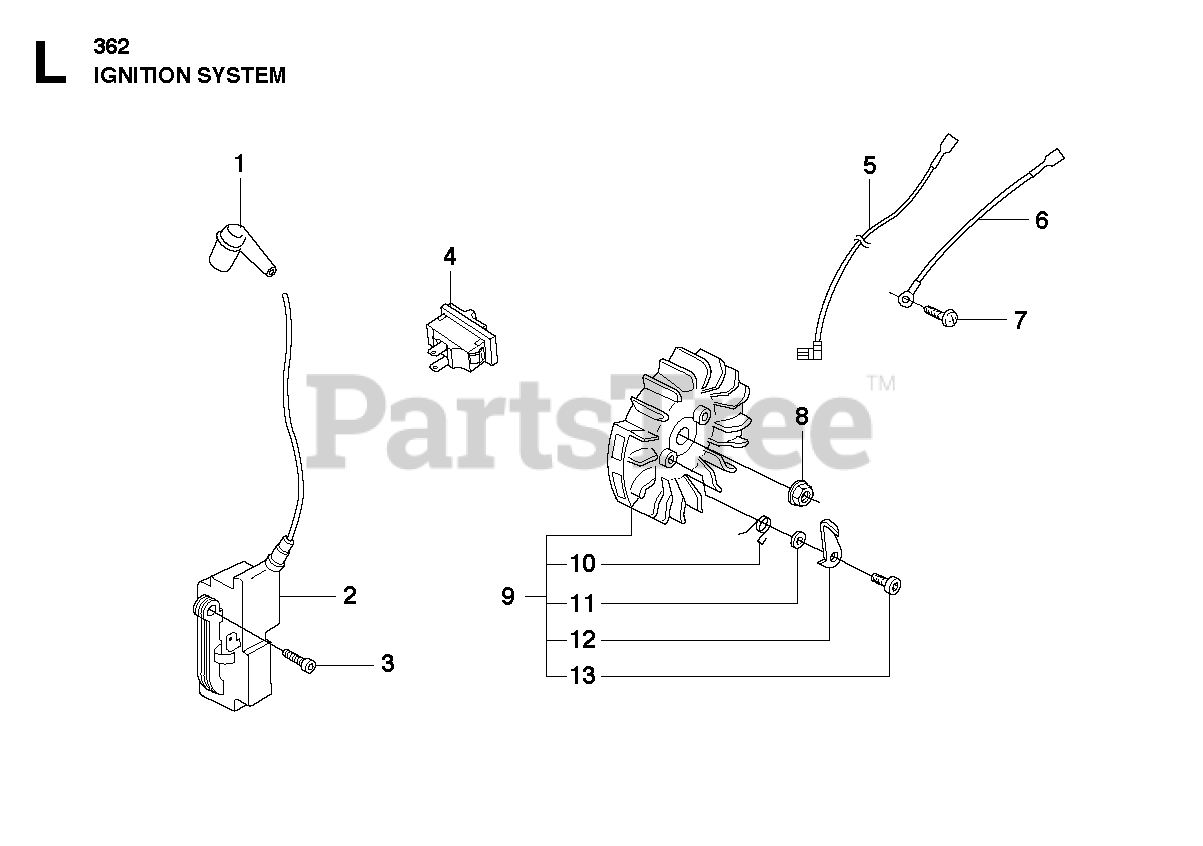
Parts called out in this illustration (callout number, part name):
1	SPARK PLUG CONN. KIT
2	IGNITION MODULE
4	START/STOP SWITCH
8	NUT W/ WASHER
10	SPRING
11	WASHER
12	PAWL
13	SCREW M5X14
